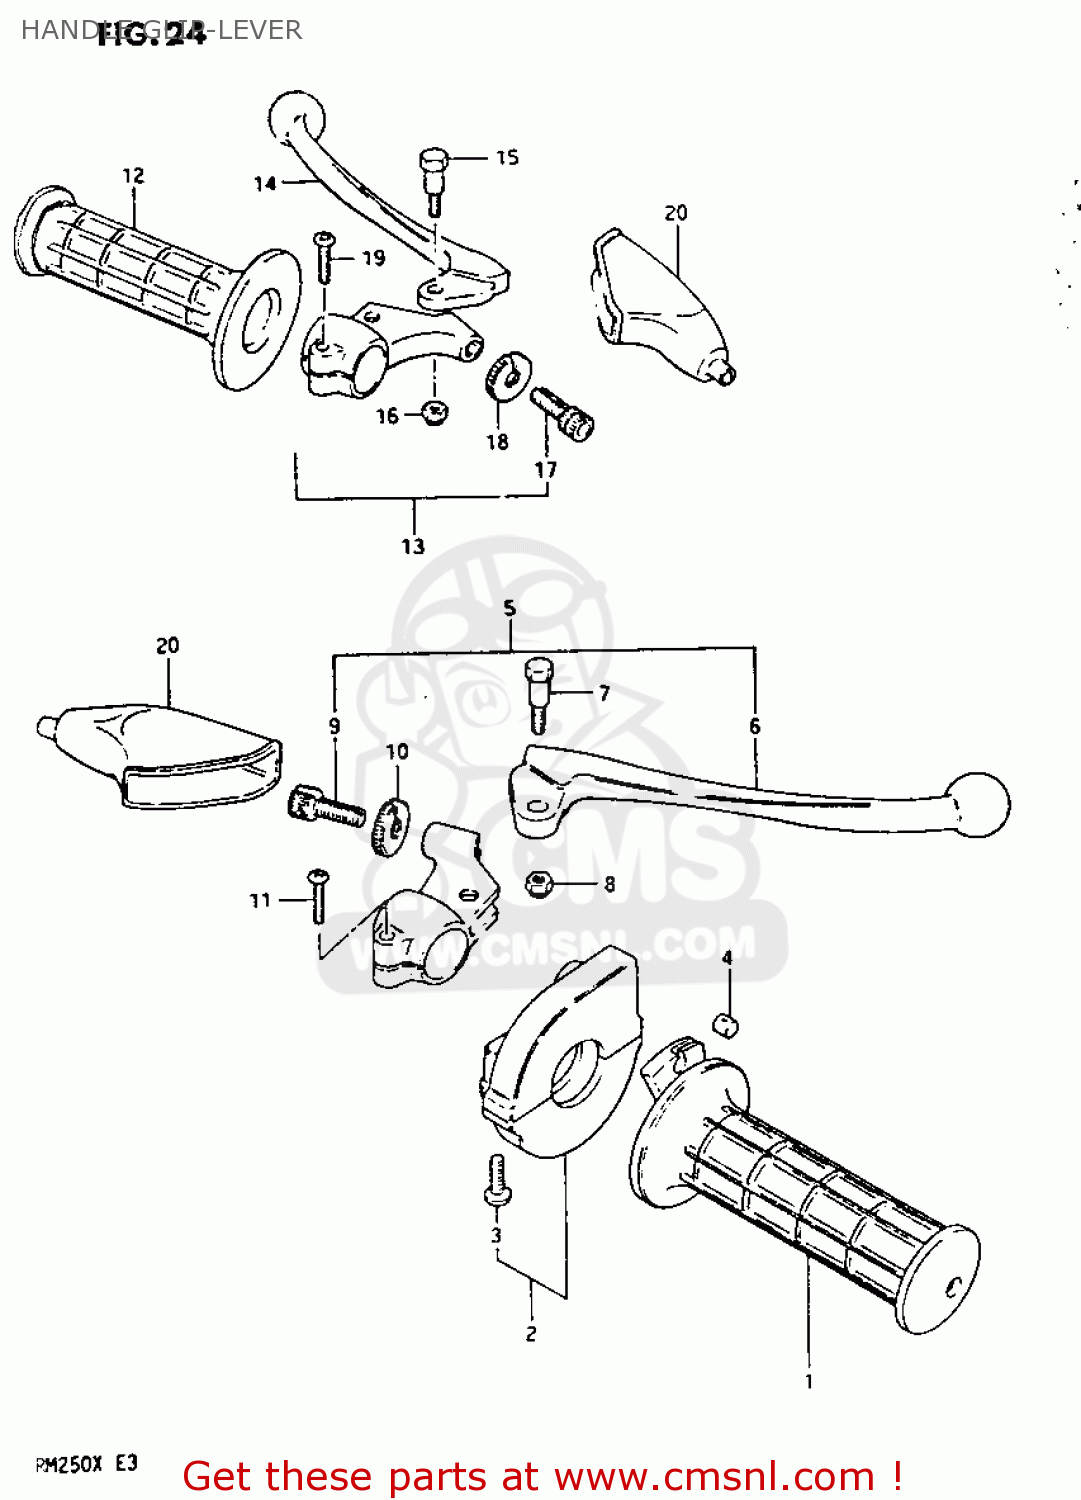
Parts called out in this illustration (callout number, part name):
1	GRIP,THROTTLE
2	CASE ASSEMBLY,THROTTLE
3	SCREW
4	PIECE,THROTTLE END
5	LEVER ASSEMBLY,BRAKE
6	LEVER,BRAKE
7	BOLT,LEVER PIVOT
8	NUT 6MM
9	ADJUSTER,CABLE
10	NUT,CABLE ADJUSTER
11	SCREW
12	GRIP,LEFT
13	LEVER ASSEMBLY,CLUTCH
14	LEVER,CLUTCH
15	BOLT,LEVER PIVOT
16	NUT 6MM
17	ADJUSTER,CABLE
18	NUT,CABLE ADJUSTER
19	SCREW
20	COVER,CLUTCH LEVER
